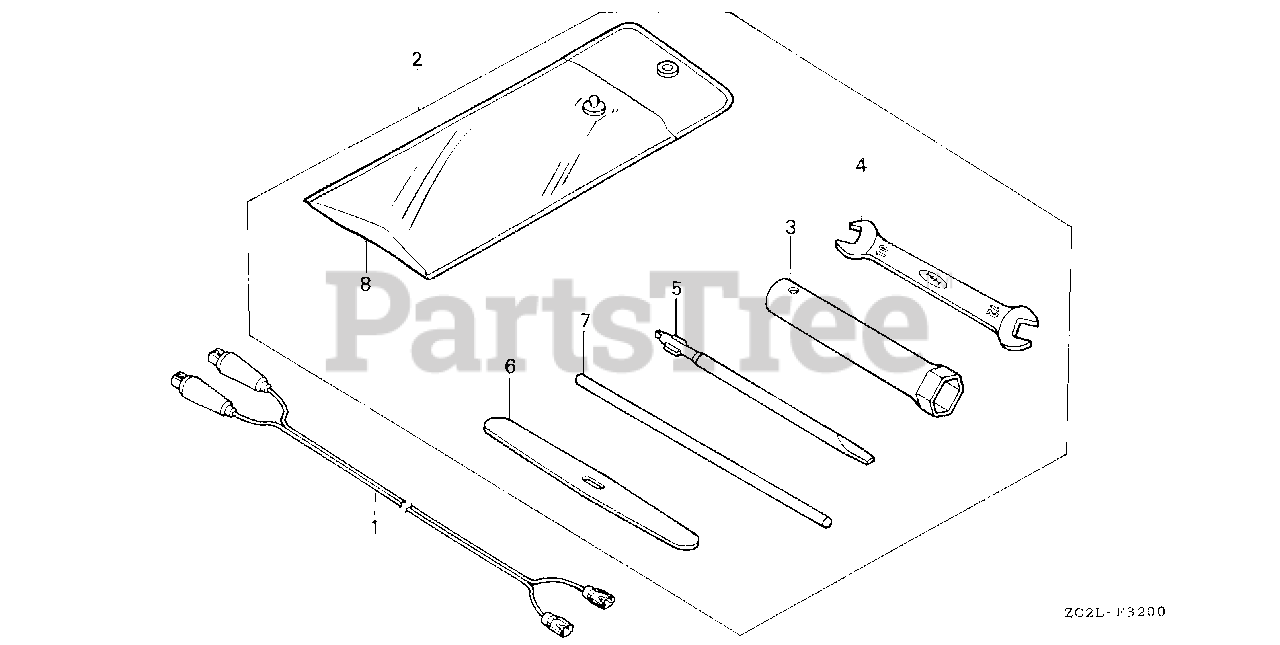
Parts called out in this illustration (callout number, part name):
1	WIRE ASSY., CHARGE
3	WRENCH, PLUG
7	BAR A, HANDLE
